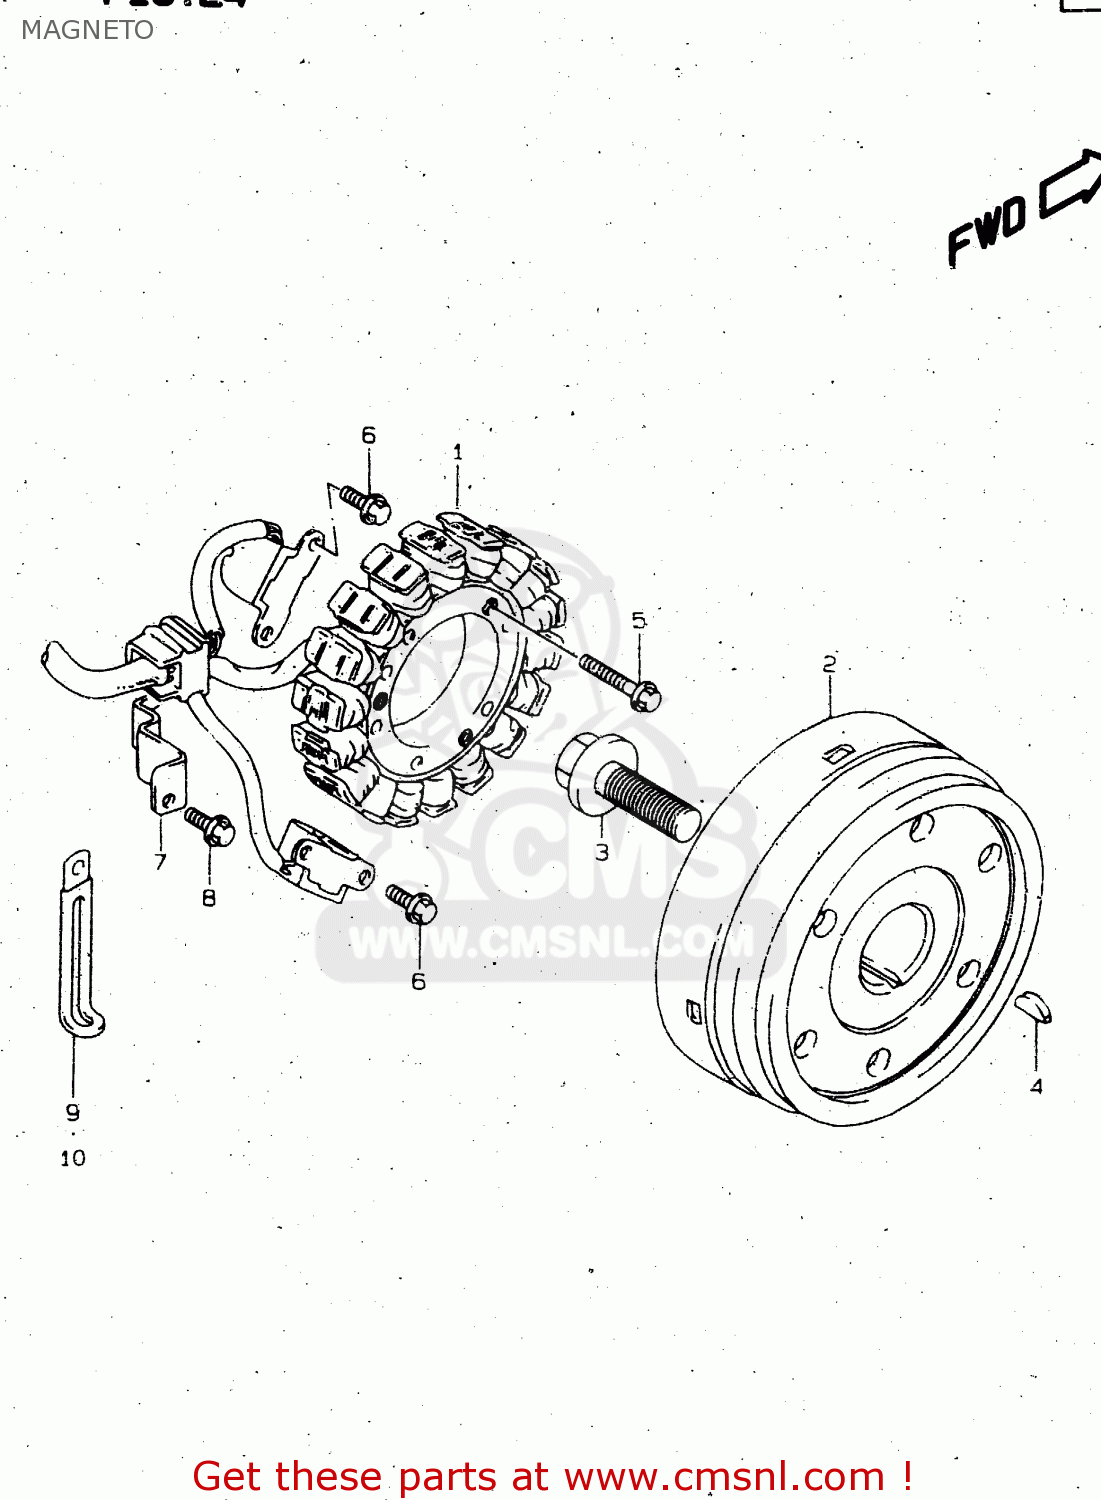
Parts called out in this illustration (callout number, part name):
1	STATOR ASSEMBLY
2	ROTOR ASSY
3	BOLT(14X43)
4	KEY
5	BOLT,G/S SWITC
6	BOLT
7	CLAMP,MAGNETO LEAD WIRE
8	BOLT
9	CLAMP(L:65 T:0.8)
10	CLAMP(L:65)
